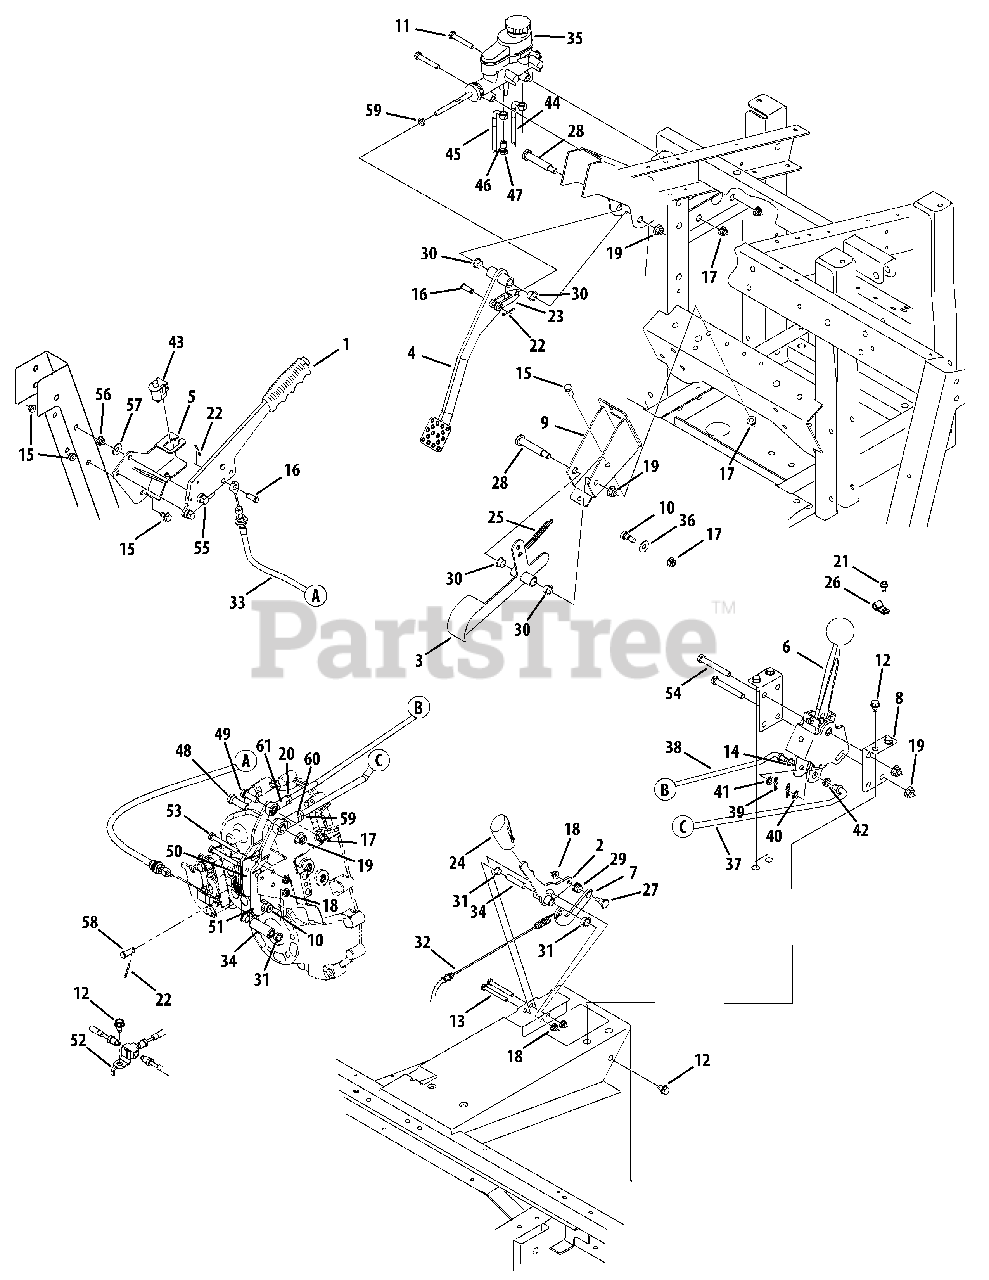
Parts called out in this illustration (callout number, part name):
1	Lvr Assembly, Brake
6	Shft Assembly, Hurst, 4x4
6	Shft Assembly, Hurst, 4x2
7	Plt, Pawl, Over Center
10	Scr, Shldr, .372 X .375, 5/16-18
11	Screw, 5/16-18, 2.00, Gr5, Patch
12	Scr, Tt, 5/16-18, 0.500
13	Screw, 1/4-20, 2.25, Gr5, Std
14	Brg., Flange, .315 ID
15	Screw, 5/16-18, .75, Gr5, Std
16	Pin, Clevis, 312 Od X 1.0"
17	Nut, Flglk, 5/16-18
18	Nut, Flglk, 1/4-20, Grf, Nylon
19	Nut, Flglk, 3/8-16, Grf, Nylon
20	Nut, Jam, 5/16-24, Gr5
21	Screw, Tt, 1/4-20 x .500
22	Pin, Cot, 3/32, 1.0
23	Yoke, 5/16-24
24	Hndl, Selct
25	Spr, Extn, .38 Od X 3.6
26	Clamp, Hose
27	Scr, Shldr, .375x.380, 1/4-20
28	Scr, Shldr, .500 X 2.230, 3/8-16
29	Plastic Bushing .380 Id
30	Brg, Flg, Nyliner, .500idx.34lg
31	Brg, Flg, .375 X .580 X .250
32	Cbl, Cont, Diff, Lock
33	Cbl, Cont, Park, Brake, 4x4
34	Spcr, Pivot, Diff Lock
35	Cyl, Master, Tandem, Hayes
36	Wash, Flat, .349 X .879 X .063
37	Link, Shft, F N R
38	Link, Shft, Hi Lo, 4x4
39	Pin, Cotter, 1/16 x .75
39	Pin, Cotter, .072 Dia. x 1.13 Lg.
40	Wash, Flat, .385 X .62 X .063
41	Wash, Flat, .330 X .630 X .0635
42	Brg, Flg, .377 Id
43	Switch
44	Hose, Brake, Master Cyl, Front
45	Hose, Brake, Master Cyl, Rear
46	Ftg, Banjo Ftg Bolt, M10 x 1.00
47	Ftg, Banjo Ftg Crush Wash
48	Screw, 3/8-16 x 1.25
49	Screw, 5/16-18 x 1.25
50	Lvr., Assembly, Shift, Hi-Lo, 4x4
51	Lvr., Assembly, Shift, F N R
52	Ftg., Tee, -3, 45 Deg Flare
53	Screw, 1/4-20 x 2.50
54	Screw, 3/8-16 x 2.75
55	Screw, 5/16-18 x 2.00
56	Nut, Jam, 5/16-18
57	Washer, Flat, .344 x .688 x .065
58	Pin, Clevis
59	Nut, Jam, 3/8-24
60	Rod, End, 3/8 ID
61	Rod, End, 5/16 ID
